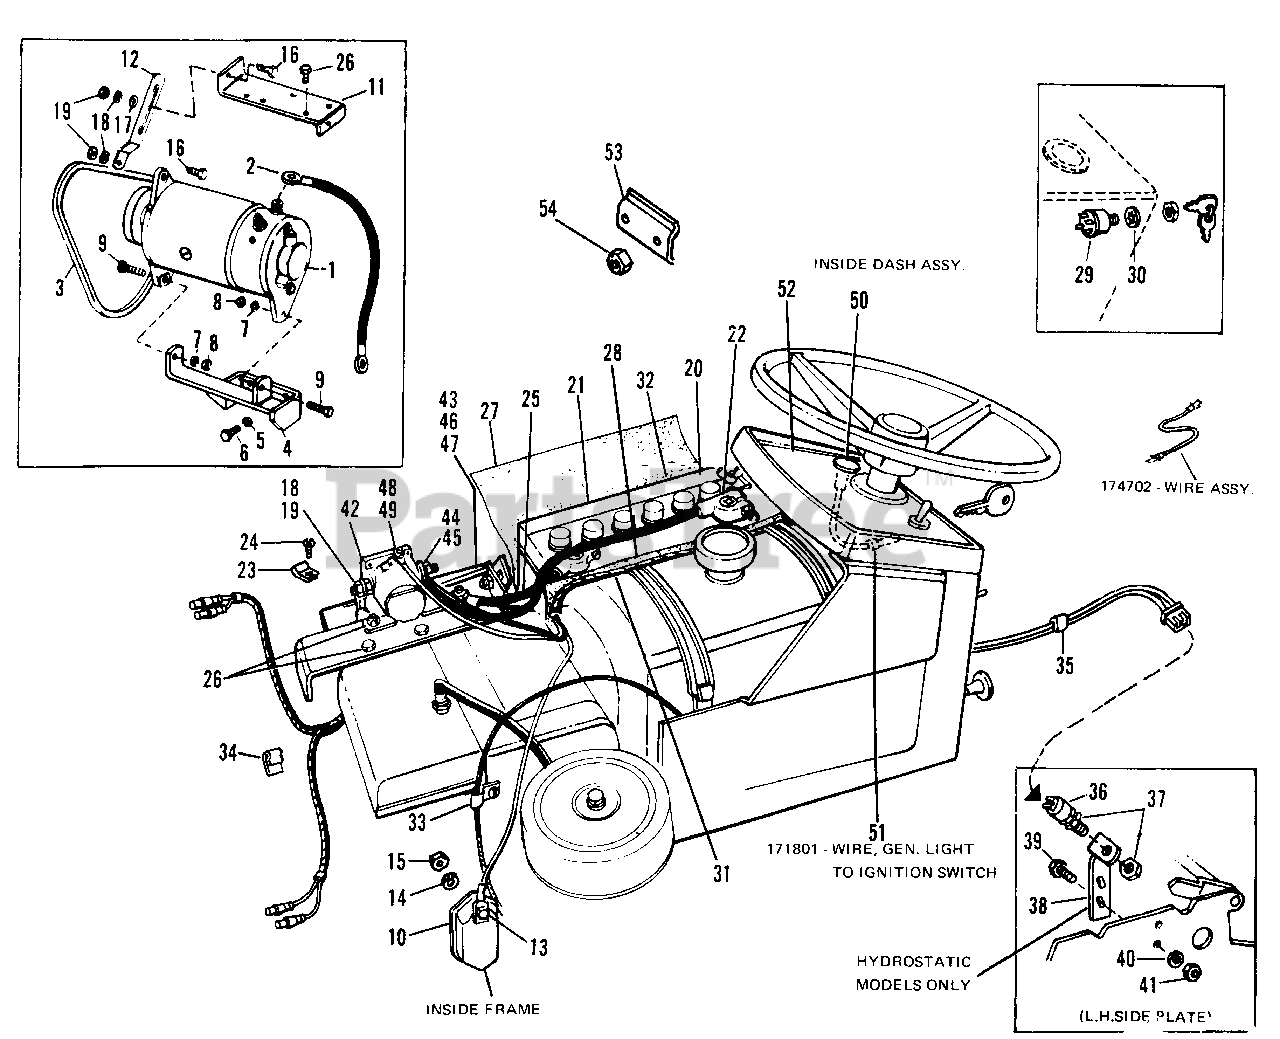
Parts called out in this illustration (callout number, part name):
1	Motor-Generator
2	Generator Start Cable
3	V-BELT, 39.12"
4	Support Assy.
5	Lock Washer, 5/16"
6	Hex Cap Screw, 5/16"-18 x 3/4"
7	Lock Washer, 5/16"
8	Full Hex Nut, 5/16"-18
9	Hex Cap Screw, 5/16"-18 x 1-1/4"
10	Voltage Regulator
12	Belt Tightener
13	Hex Cap Screw, 1/4"-20 x 3/4"
14	Lock Washer, 1/4"
15	Full Hex Nut, 1/4"-20
16	Hex Cap Screw, 5/16"-18 x 3/4"
17	Plain Washer, 5/16"
18	Lock Washer, 5/16"
19	Full Hex Nut, 5/16"-18
21	Film, Battery
22	Cable (Battery to Solenoid)
23	Wire Clamp (Generator Cable)
24	Rd. Hd. Screw 10-24 x 1/2"
25	Cable (Battery to Ground)
26	Screw Hex Thread Forming, 1/4"-20 x 1/2"
27	Battery Insulation
28	Fuel Tank Insulation
29	Starter Switch w/Keys
30	Lock Washer Int., 9/16"
31	Harness Assembly
34	Speed Clip
36	Safety Switch
37	Nut
38	Switch Support
39	Hex Cap Screw, 5/16"-18 x 3/4"
40	Lock Washer, 5/16"
41	Full Hex Nut, 5/16"-18
43	Screw Hex Thread Forming, 1/4"-20 x 1/2"
44	Full Hex Nut, 10-32
45	Lock Washer, ext. No. 10
46	Full Hex Nut, 5/16"-18
47	Lock Washer, 5/16"
48	Lock Washer, 1/4"
49	Full Hex Nut, 1/4"-20
50	Indicator Lamp Assy.
51	Wire Ignition to Gen. Light
52	Circuit Breaker
53	Battery Clamp
